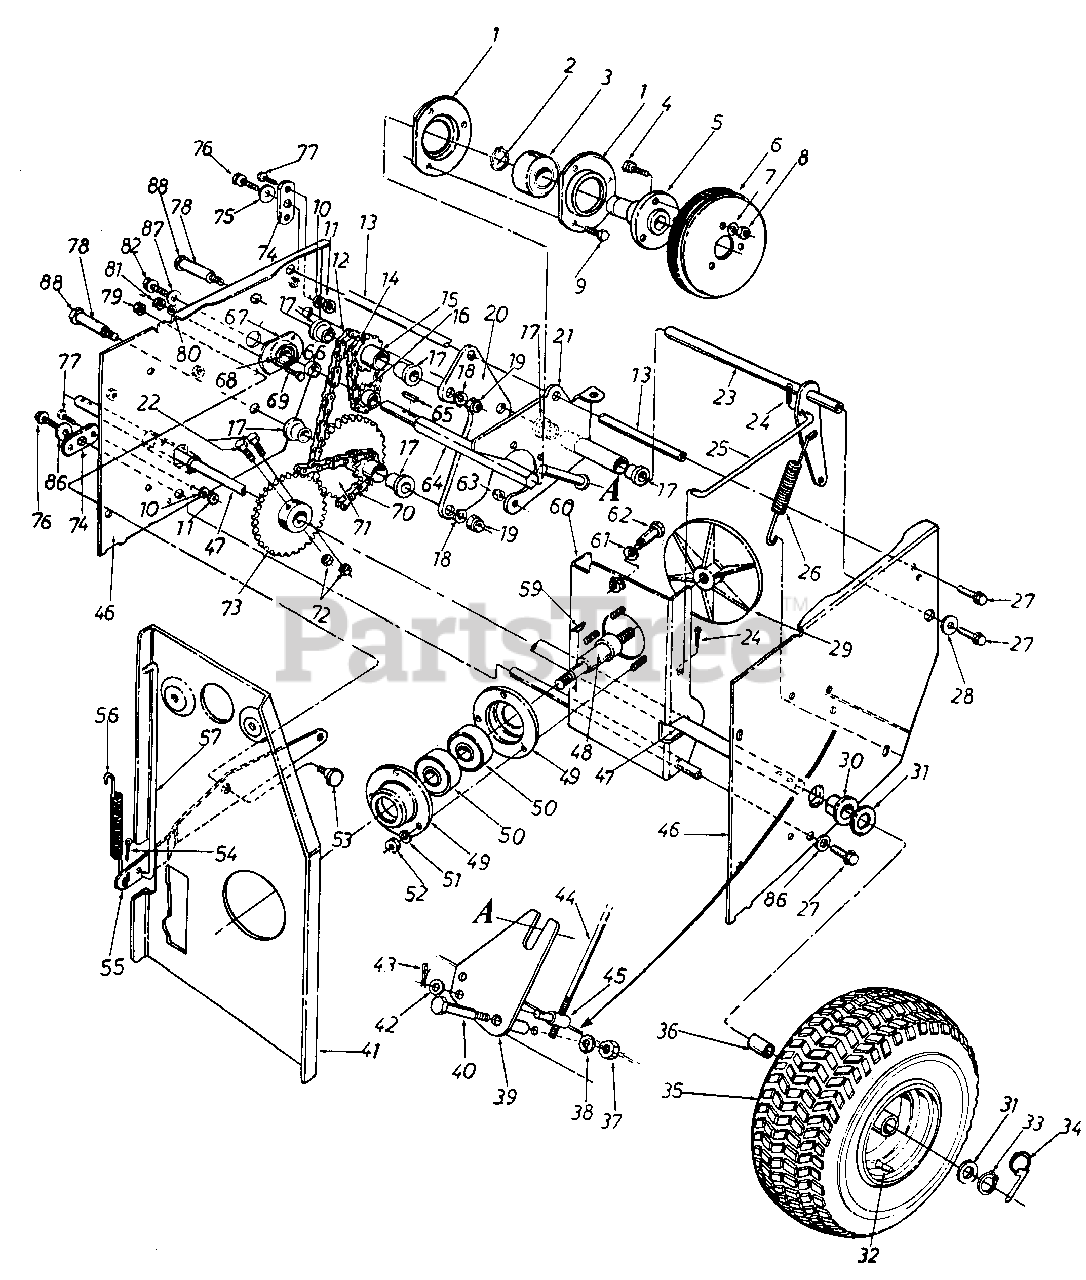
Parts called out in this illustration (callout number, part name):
1	HOUSING-BRG
2	RING-SNAP FOR 1.00 DIA SHAFT
3	BEARING-BALL
4	SCREW-HEX SEMS 5/16-18 X .75
5	ADAPTER-FRICTION WHL
6	WHEEL ASSY-FRICTION
7	WASHER-LOCK-5/16
8	NUT-HEX 5/16-18
9	SCREW-HEX 1/4-28 X .62
10	LOCK WASHER 1/4 DIA
11	NUT-HEX 1/4-20
12	CHAIN 1/2" PITCH X 43 LINK
13	AXLE-SLIDING SUP
14	#41 CHAIN 1/2 PITCH X 19 LINKS
15	SPROCKET & HUB ASSY-9 & 147
16	SPROCKET-CENTER #41-8T
17	BEARING-FLANGE .630 ID
18	WASHER-HDL 3/8
19	NUT-HEX INS L-3/8-24
22	SCREW-HEX 5/16-24 X 1.75
23	BRACKET ASSY-DR CLUTCH
24	PIN-INTERN COT-5/16 DIA
25	ROD-CLUTCH-DR
26	SPRING-IDLER EXTN
27	SCREW-HEX 5/16-18 X .62
28	WASHER-FL-.344 X .62
29	PLATE-ALUM DRIVE
30	BEARING-FLANGE
31	WASHER-FL-1.03 ID X 1.62 X .03 HD
32	VALVE-TUBELESS AIR
33	RING-SNAP FOR 1.00 DIA SHAFT
34	PIN-CLICK-5/16X2.34
35	WHEEL ASSY-SNOW HOG
37	NUT-HEX JAM 3/8-18
38	WASHER-LOCK-3/8
41	BRACKET ASSY-ENG
42	WASHER-FL-.344 X .62
43	PIN-COTTER-3/32 DIA X .75
44	ROD-SHIFT
45	FERRULE-ADJ
46	FRAME ASSY
47	AXLE-FREE WHEELING
48	SPINDLE-DRIVE PLT
49	HOUSING-BRG
50	BEARING-BALL
51	WASHER-LOCK-5/16
52	NUT-HEX 5/16-18
53	SCREW-SHLD .625 DIA X .163
54	PIN-INTERN COT-5/16 DIA
55	BRACKET-AUG CLUTCH
56	SPRING-EXTENSION
57	ROD-AUG CLUTCH
59	KEY-3/16 X 5/8
62	SCREW-SHLD .498 DIA X 1.640
63	NUT-HEX INS-L
64	SHAFT-HEX
65	KEY-HI-PRO #4-3/32X5/8 DIA-HDN
67	HOUSING-BRG
68	BEARING-BALL
69	SCREW-HEX 1/4-20 C .62
70	#420 CHAIN 1/2 PITCH X 37 LINKS
71	SPROCKET & HUB ASSY-9 & 32T
72	NUT-HEX INS JAM LOCK 5/16-24
73	SPROCKET ASSY-28T
74	BRACKET-PIVOT AXLE
75	WASHER-FL-.344 X .62
76	SCREW-HEX 5/16-18 X .62
77	SCREW-HEX 1/4-20 C .62
78	HUB-SPROCKET
79	NUT-HEX CENTER L-3/8-16
80	LOCK WASHER 1/4 DIA
81	NUT-HEX 1/4-20
82	SCREW-HEX 5/16-18 X .62
86	WASHER-FL-.344 ID X .88 OD X .063
87	WASHER-BELL .337 X .867 X .057
88	SCREW-HEX 3/8-16 X 2.75
